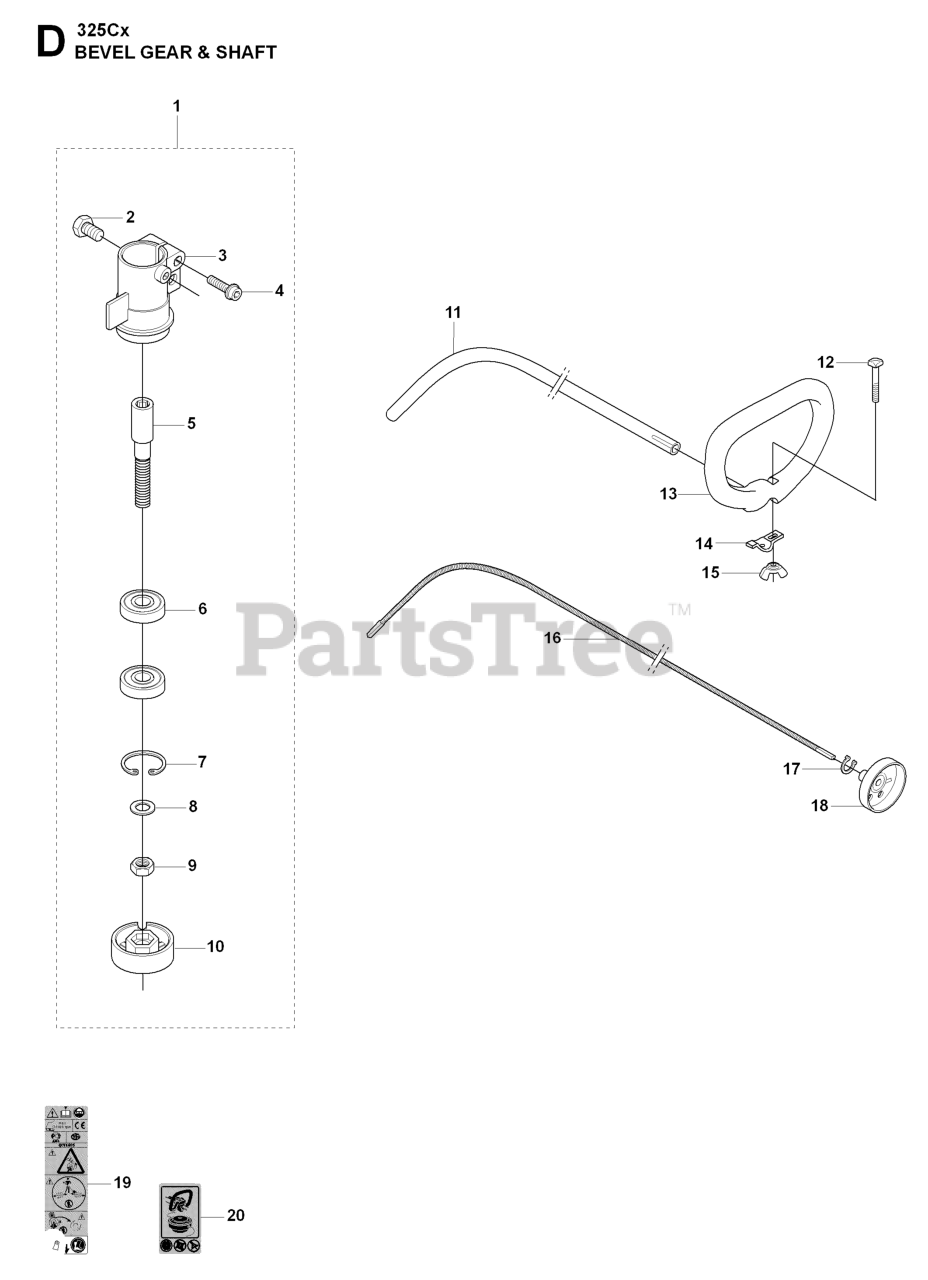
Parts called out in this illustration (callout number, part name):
1	BEARING HOUSING
2	SCREW M6S 6X20
3	BEARING HOUSING
4	SCREW
13	HANDLE, LOOP
14	HOLDER
16	DRIVE SHAFT
17	RETAINING RING SGA 10
18	CLUTCH DRUM
19	WARNING DECAL 323L/326L
20	DECAL WARNING "NO BLADES"
